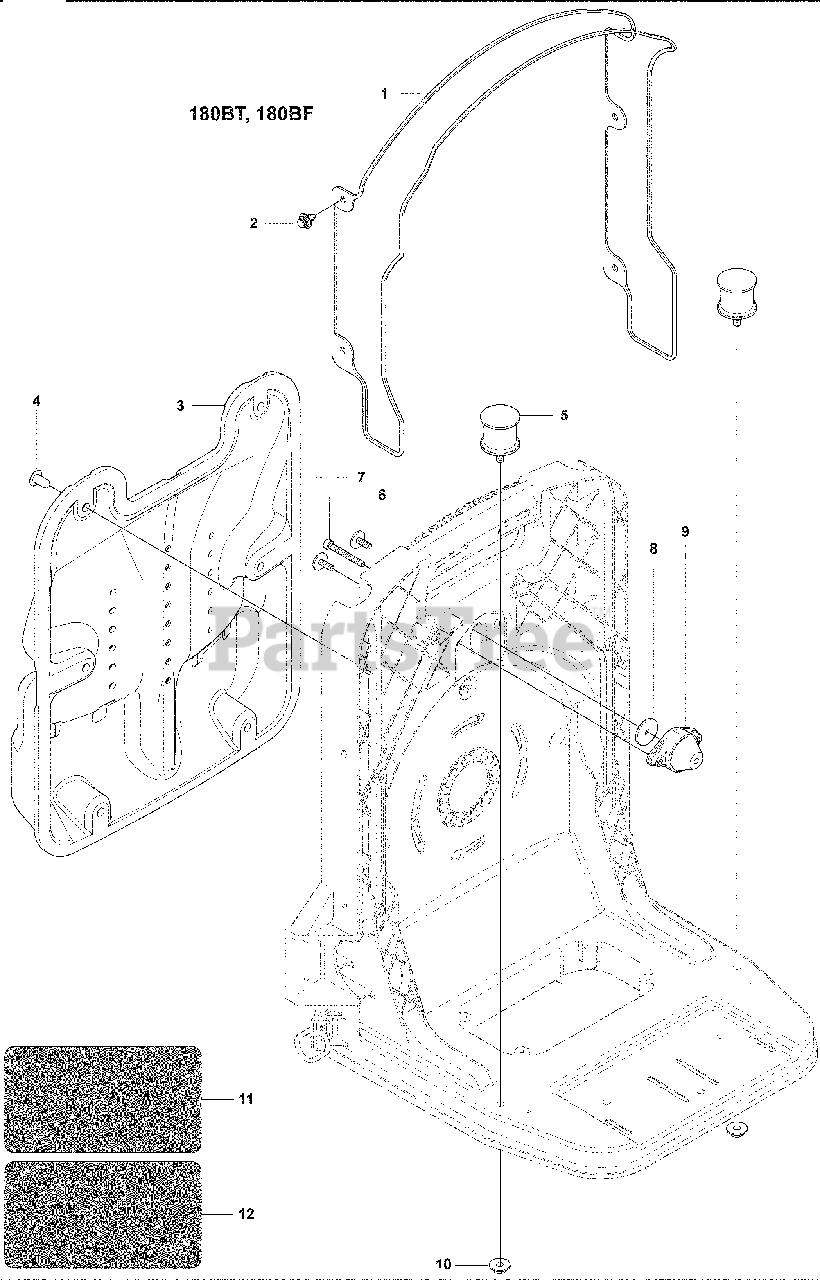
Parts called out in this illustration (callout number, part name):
2	Clip
4	Clip
5	Damper
6	Clip
7	Bolt
8	Washer
9	Upper Damper
10	Nut
11	LABEL
12	LABEL
